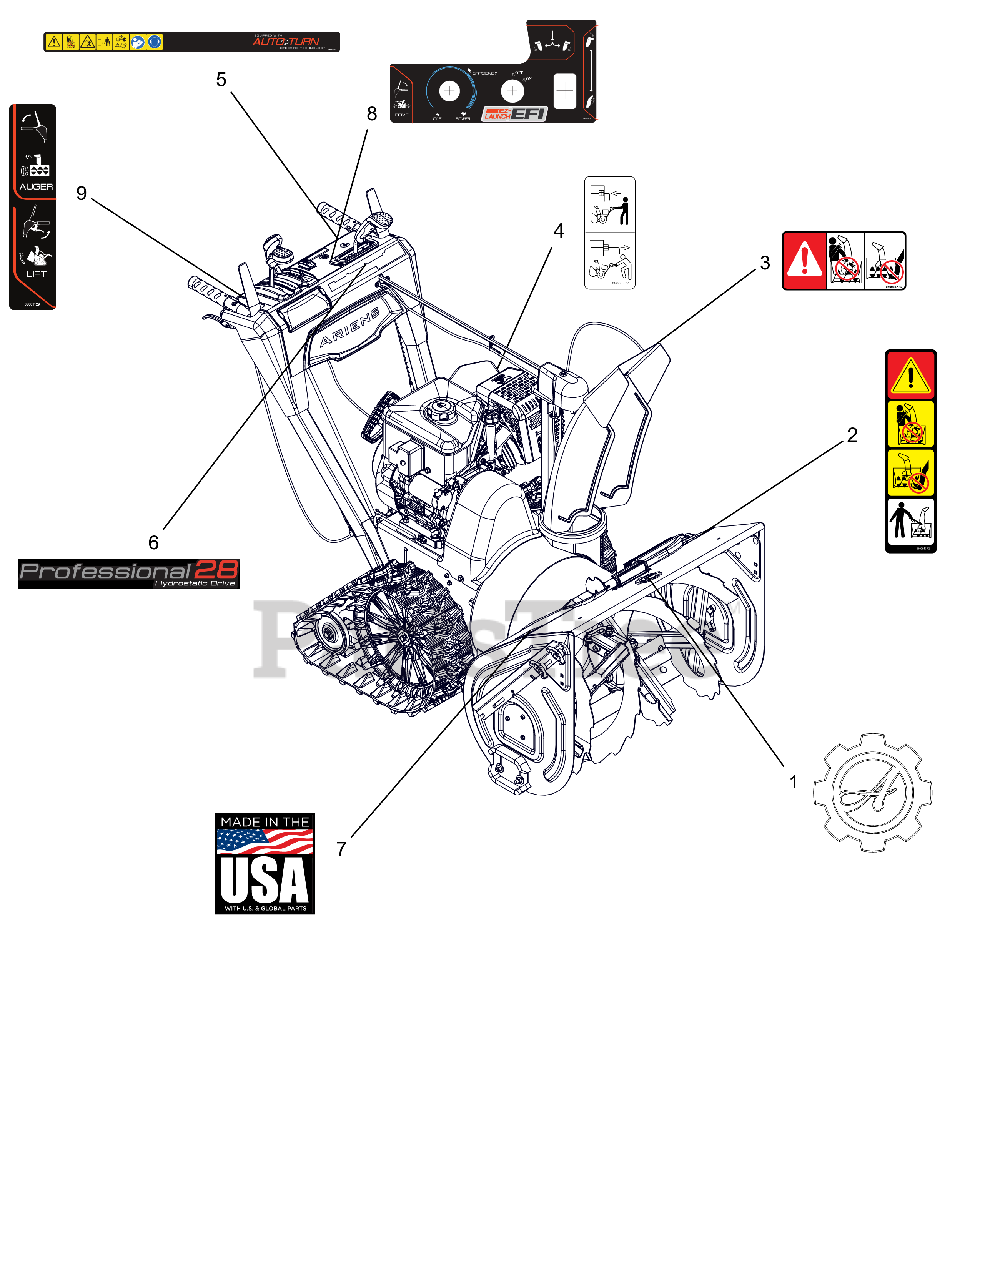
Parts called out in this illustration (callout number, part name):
1	DECAL, ARIENS-GEAR BADGE -THK
2	DECAL, DANGER - ROTATING PARTS
3	DECAL, DANGER
4	DECAL, BYPASS
5	DECAL,DASH - SAFETY/EFI
6	DECAL, DASH - PRO HYDRO 28
7	DECAL, MADE IN USA
8	DECAL, CONTROL - QT EFI W/GEL
9	DECAL,CONTROL-RH TRACK
